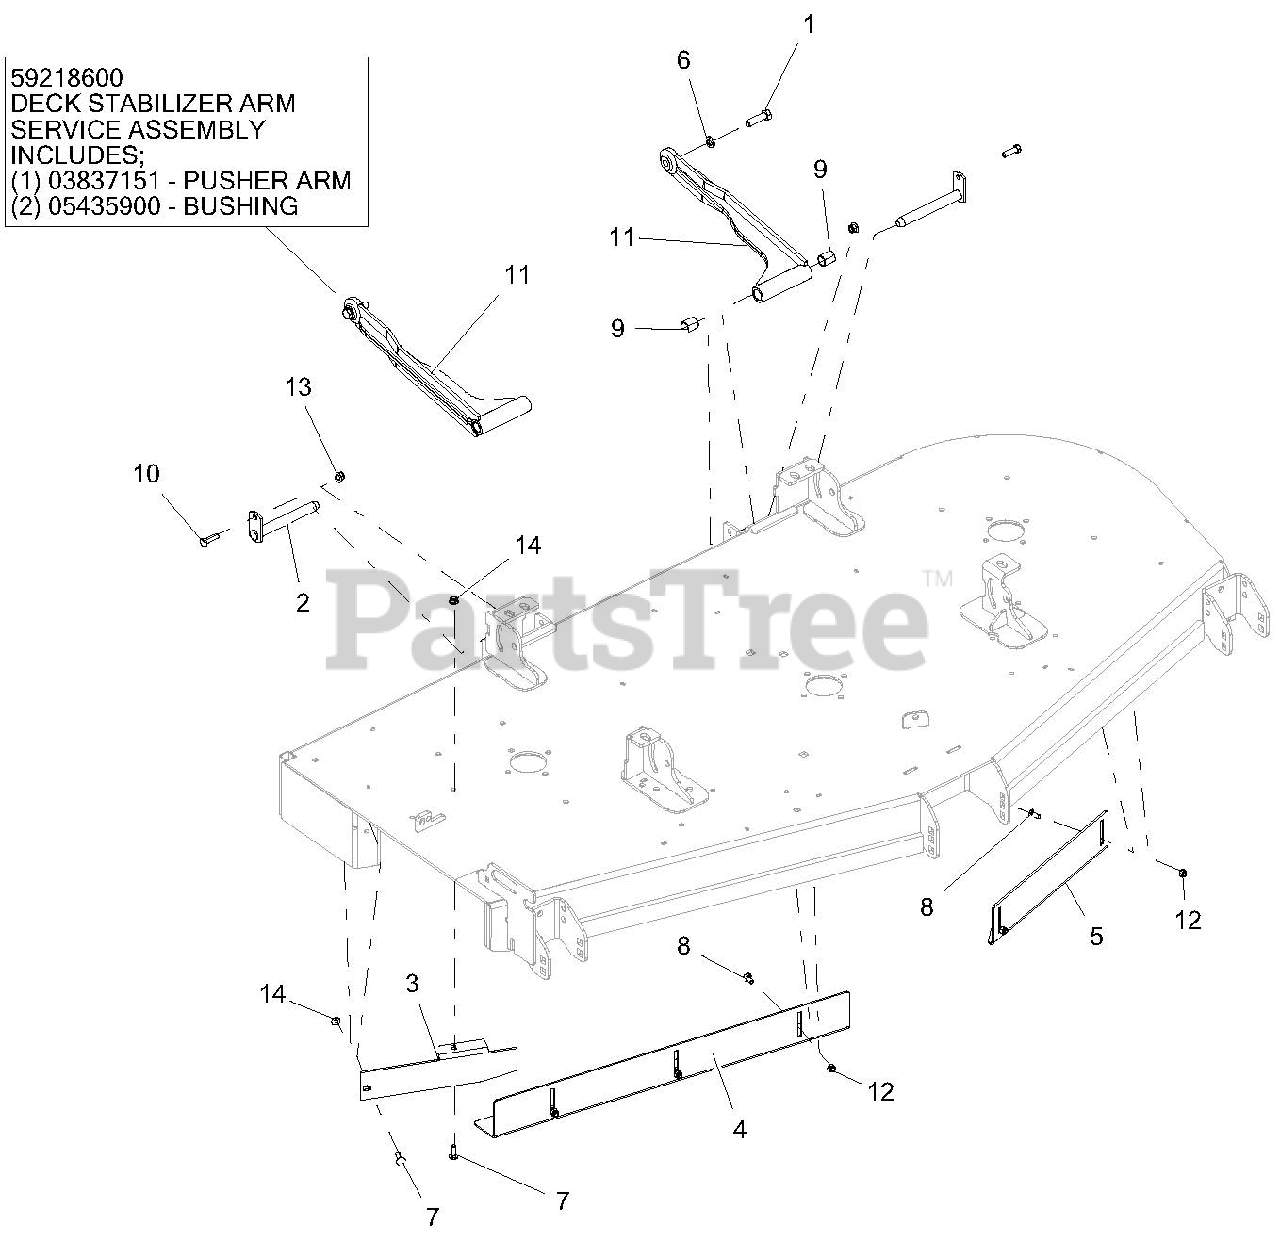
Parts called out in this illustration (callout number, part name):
1	BLT-HEX .50-13X1.75 GR5 YWZC EP80
2	WLDMT, MOWER MTG. PIN
3	BAFFLE, 72" DISCHARGE-RED
4	BAFFLE, 72" RH VACUUM-BLACK
5	BAFFLE, 72" LH VACUUM-BLACK
6	WSHR-LK .50X.125 REG YWZC
7	BLT-RDHDSQSHNK .31-18X1.00 G5 Y
8	BLT-RDHDSQNK .31-18X.75 G5 YWZC
9	BRG, .750 X .875 X 1.000
10	BLT-HEX .38-16X1.25 GR5 YWZC
11	WMT, DECK STABILIZER ARM-BLACK
11	DECK STABILIZER ARM SERVICE ASSEMBLY
11	PUSHER ARM
11	BUSHING
12	NUT-LK-NYL .312-18 YWZC
13	NUT-LK-NYL-FLG .38-16 YWZC
14	NUT-LK-NYL-FLG .31-18 YWZC
